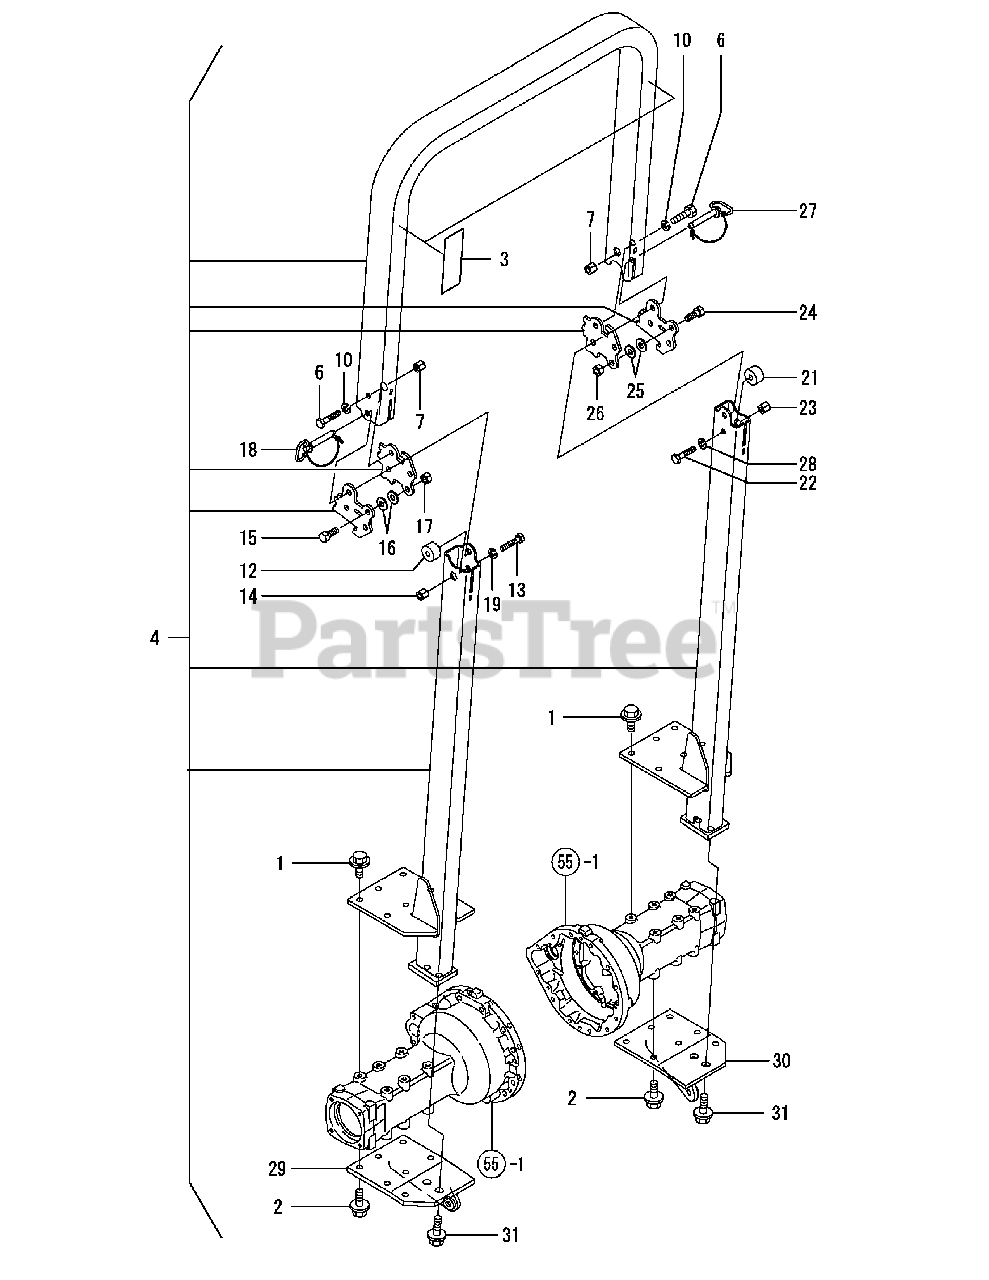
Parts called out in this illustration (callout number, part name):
3	TAPE,REFLECTION
6	BOLT 1/2-20X2.25
13	BOLT 1/2-20X2.25
15	BOLT 1/2-13X1.25
22	BOLT 1/2-20X2.25
24	BOLT 1/2-13X1.25
29	PLATE ASSY, BASE L
30	PLATE ASSY, BASE R
